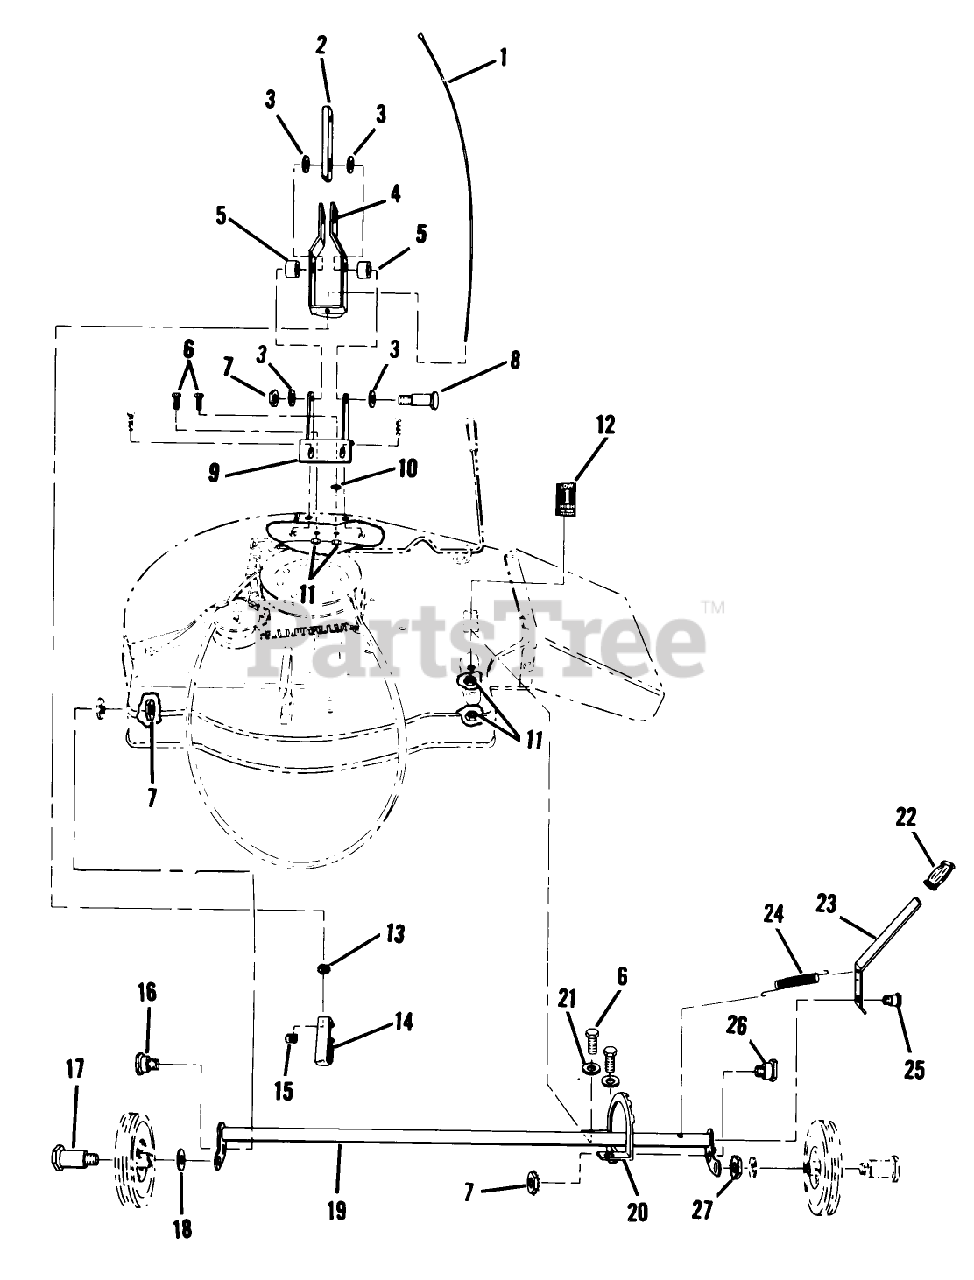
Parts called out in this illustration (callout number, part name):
1	Lift Cable Assembly
2	Bar, Hitch
3	Washer
4	Bracket, Pivot
5	Spacer
6	Bolt Hex 5/16-18
7	Nut
8	Bolt 3/8-16 x 2 1/2
9	Bracket, Deck Front
10	Lockwasher
11	Nut 5/16-18
12	Decal, Height Adjust
13	Nut 1/4-20 Keps
14	Bracket, Cable
15	Nut
16	Shoulder Bolt
17	Shoulder Bolt
18	Lockwasher
19	Tube Assembly, Height Adjust
20	Quadrant, Height Adjust
21	Washer
22	Hand Grip
25	Shoulder Bolt
26	Shoulder Bolt
27	*Nut, Jam, 3/8-24 Thd
